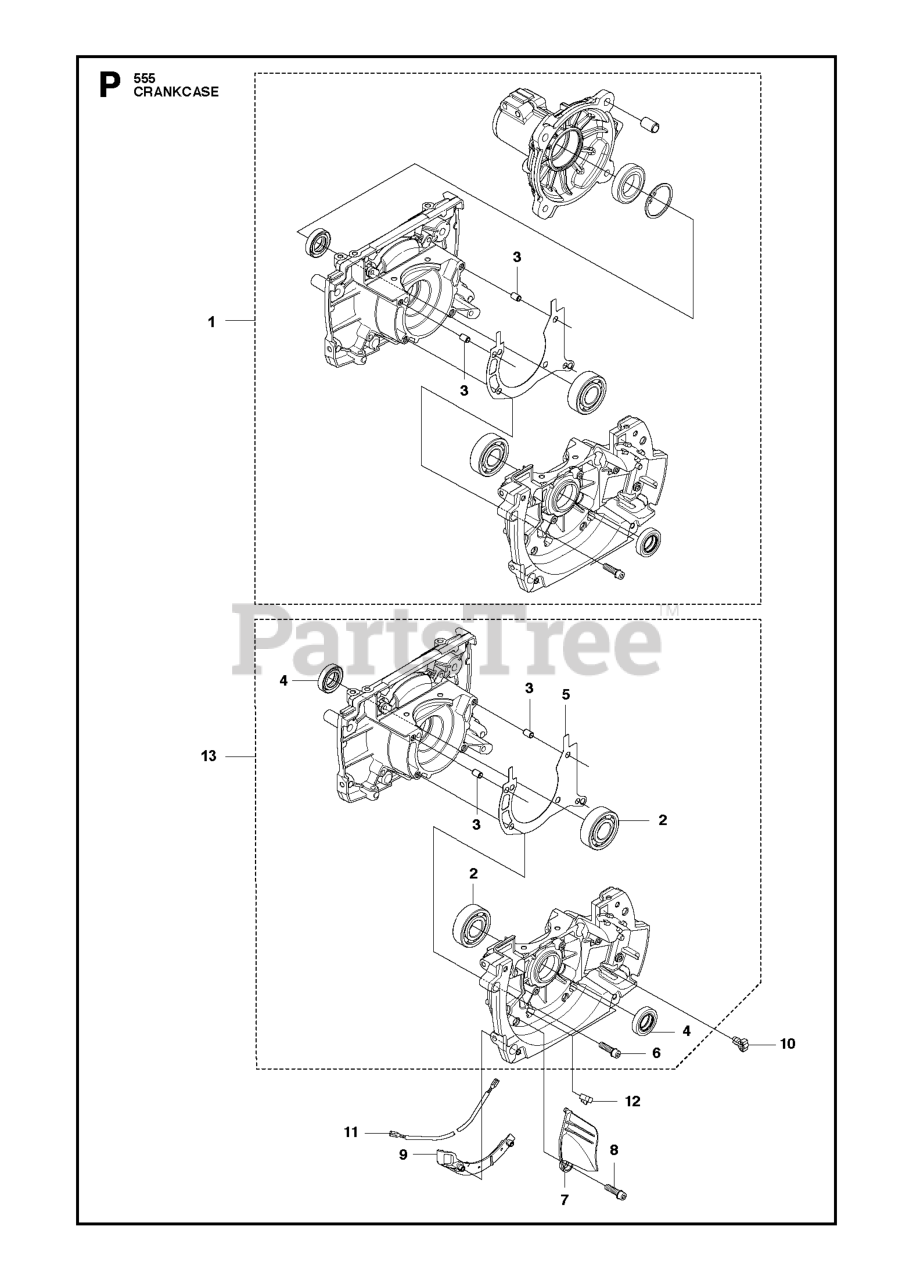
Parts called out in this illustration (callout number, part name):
2	BALL BEARING
3	PIN 5X14
3	GUIDE BUSHING
4	SEALING RING
5	Crankcases
5	CRANKCASE GASKET
9	CABLE HOLDER
11	SHORT CIRCUIT CABLE
